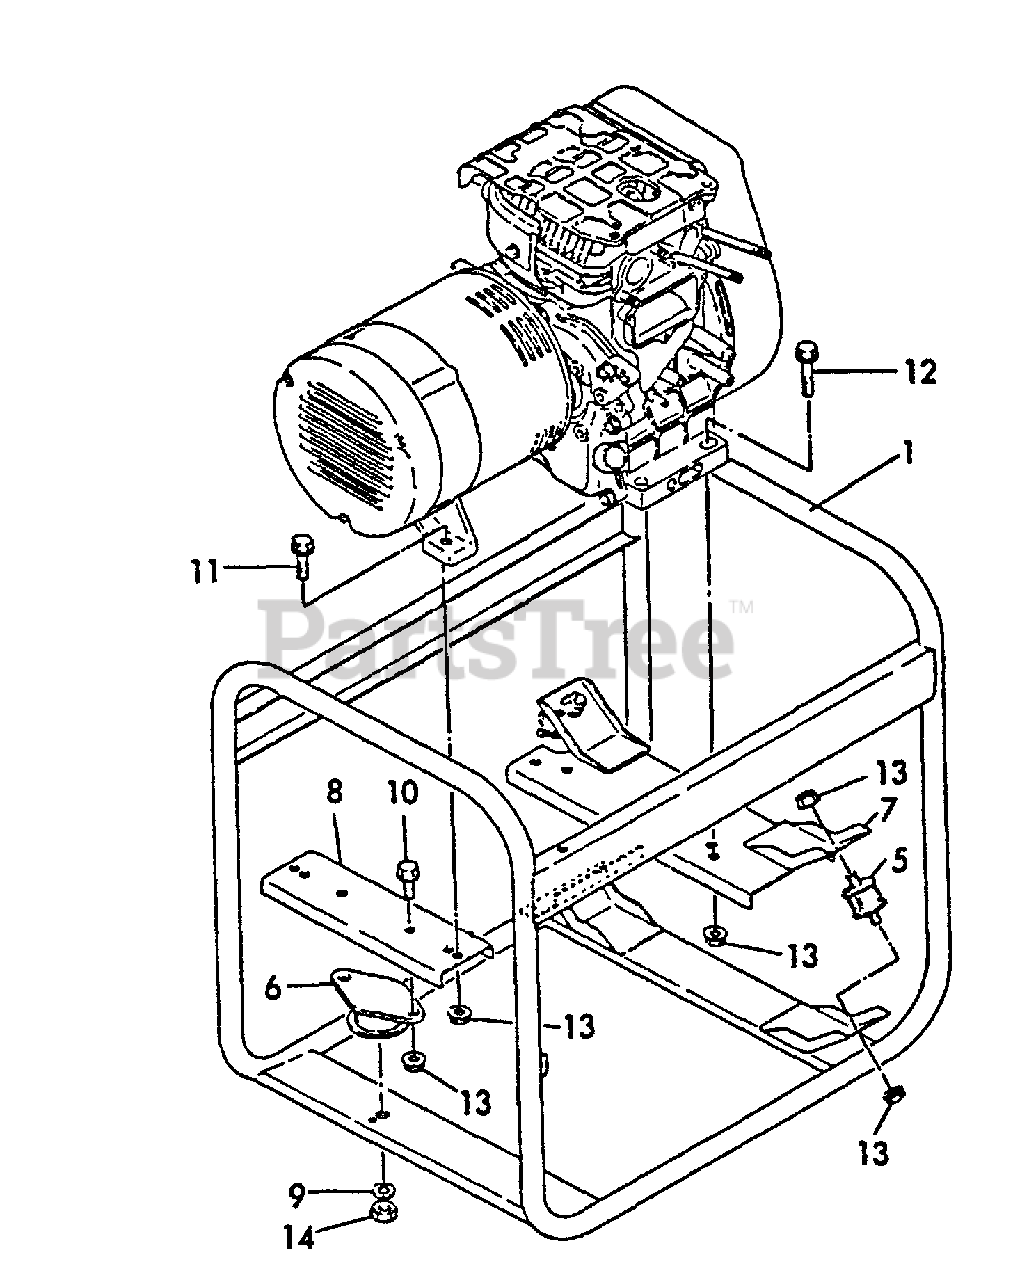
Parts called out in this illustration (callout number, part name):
1	FRAME ASSY
5	DAMPER, FRONT
6	DAMPER, REAR
7	STAY, DAMPER
8	STAY, REAR DAMPER
9	LOCKWASHER - 10
10	BOLT - 8×20 -- PLATED
11	BOLT - 8×30 -- PLATED
12	BOLT - 8×38 -- PLATED
13	U-NUT M8
14	NUT - 10
